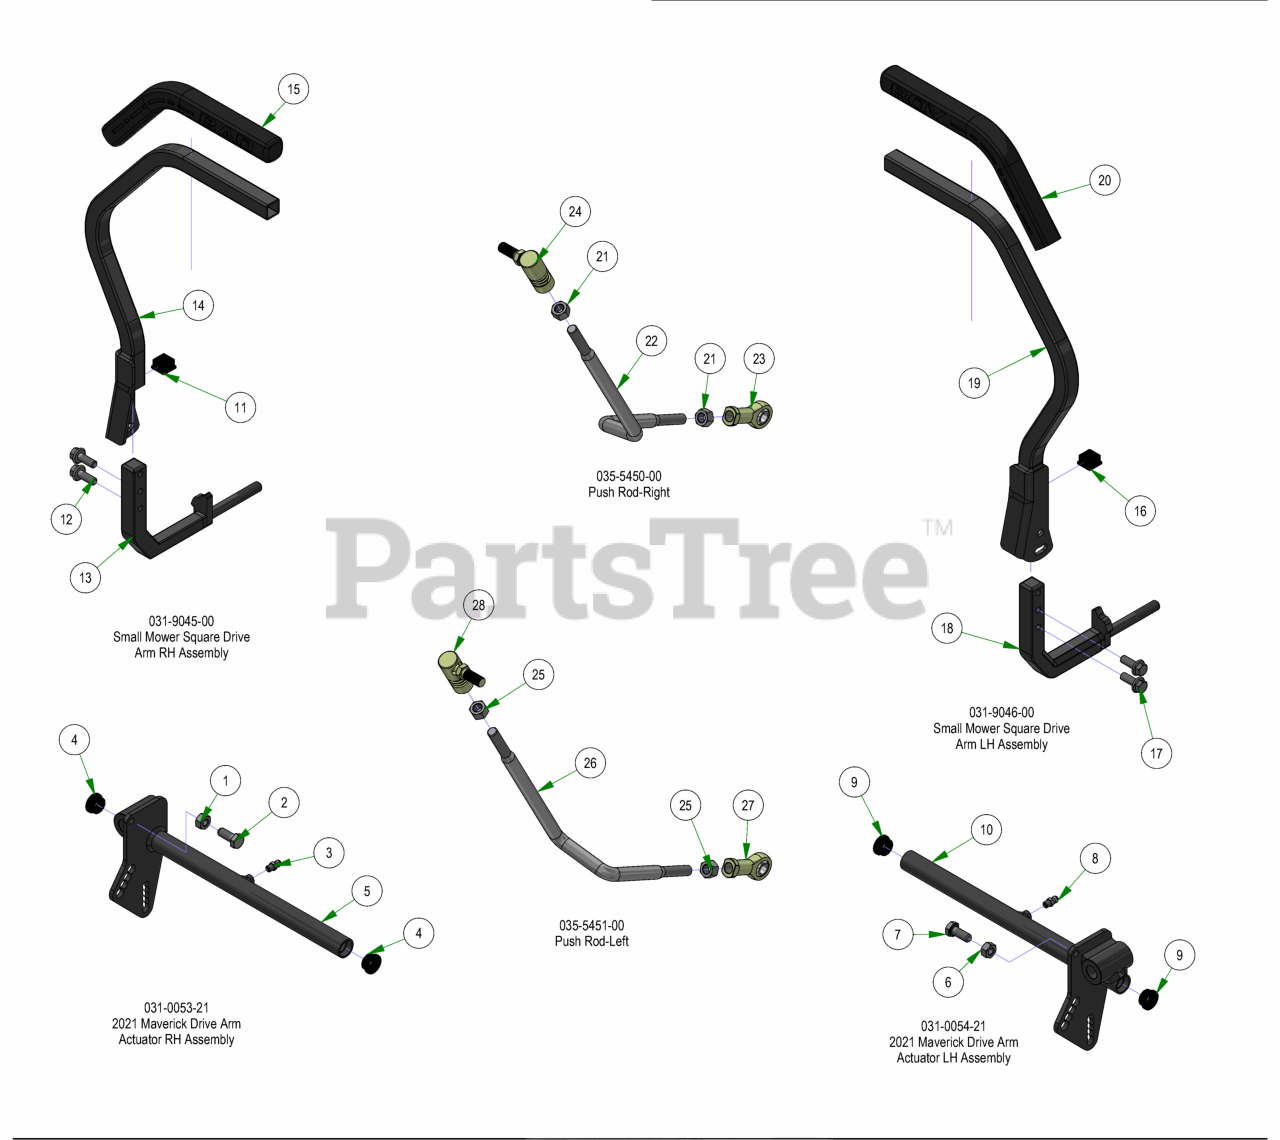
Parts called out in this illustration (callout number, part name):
1	5/16-18 HEX NUT ZINC
2	5/16-18 X 3/4 HEX CAP SCREW (GR.5) ZINC
3	1/4 DRIVE-TYPE STRAIGHT GREASE FITTING ZINC YELLOW)
4	2019 Drive Arm Bushing
5	2021 Drive Actuator RH Weldment
6	5/16-18 HEX NUT ZINC
7	5/16-18 X 3/4 HEX CAP SCREW (GR.5) ZINC
8	1/4 DRIVE-TYPE STRAIGHT GREASE FITTING ZINC YELLOW)
9	2019 Drive Arm Bushing
10	2021 Drive Actuator LH Weldment
11	9565K16_Polyethylene Square Plug
12	92323A554_Grade 5 Steel Serrated-Flange Hex Head Screw
13	Small Mower Square Drive Arm Lower RH Weldment
14	Small Mower Square Drive Arm RH Weldment
15	Grip for 031-9045-00 / 031-9046-00
16	9565K16_Polyethylene Square Plug
17	92323A554_Grade 5 Steel Serrated-Flange Hex Head Screw
18	Small Mower Square Drive Arm Lower LH Weldment
19	Small Mower Square Drive Arm LH Weldment
20	Grip for 031-9045-00 / 031-9046-00
21	3/8" Fine Threaded Jam Nut
22	Push Rod - Right (Rod Only)
23	Spherical Rod End - Outlaw
24	Quick Release Ball Joint
25	3/8" Fine Threaded Jam Nut
26	Push Rod LH (Rod Only)
27	Spherical Rod End - Outlaw
28	Quick Release Ball Joint
